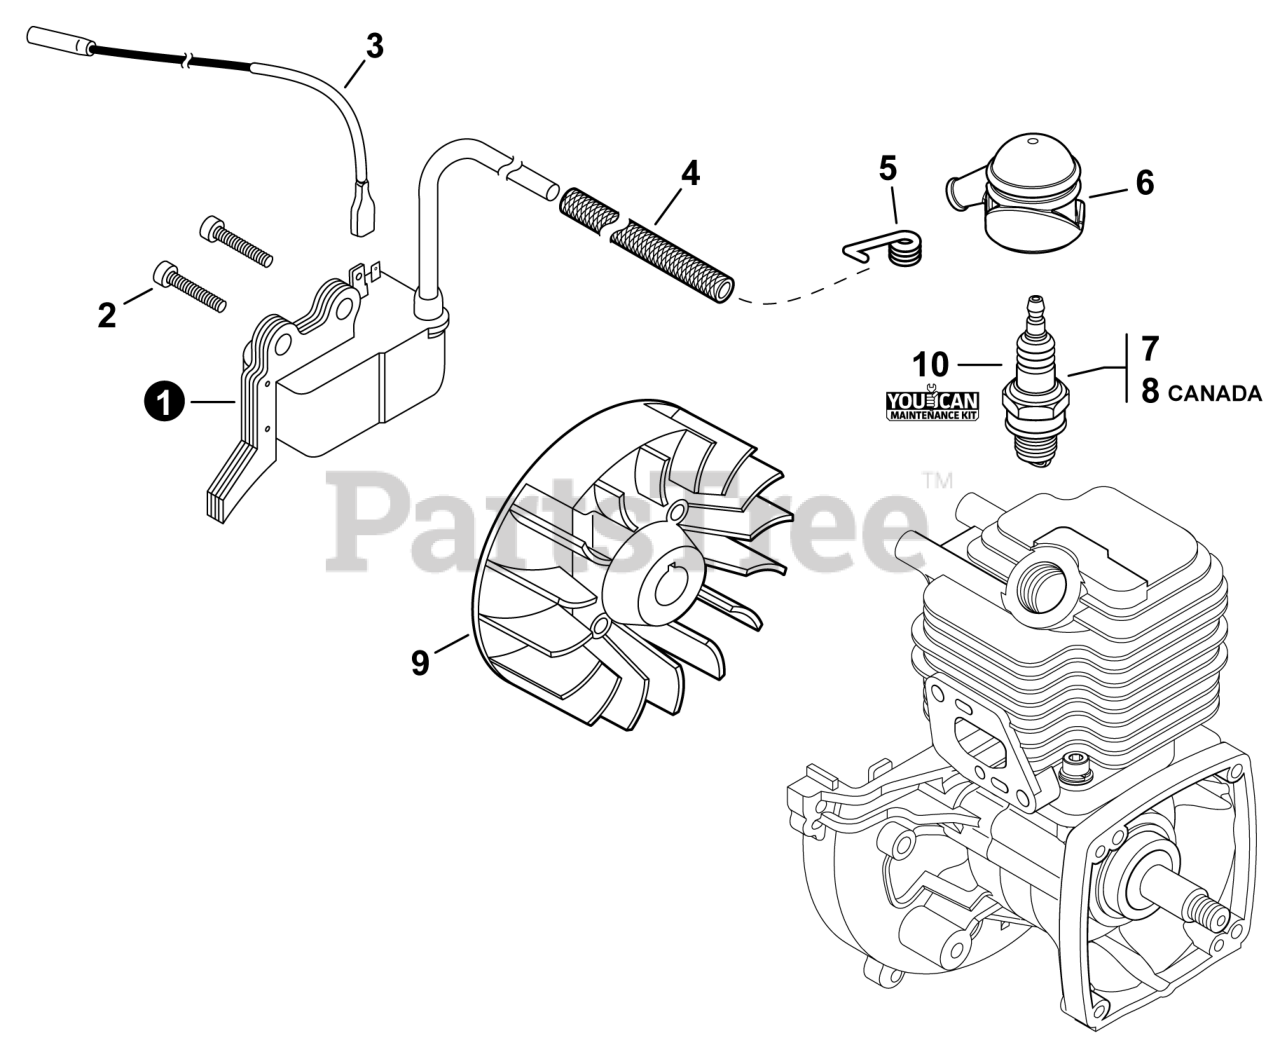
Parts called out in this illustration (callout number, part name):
1	COIL, IGNITION
2	BOLT, TORX 4x20
3	LEAD - IGNITION L= 210
4	TUBE, INSULATOR
5	TERMINAL, SPARK PLUG
6	CAP, SPARK PLUG
7	SPARK PLUG - BPM8Y
8	SPARK PLUG - BPMR8Y
9	FLYWHEEL
10	TUNE-UP KIT - YOUCAN™
